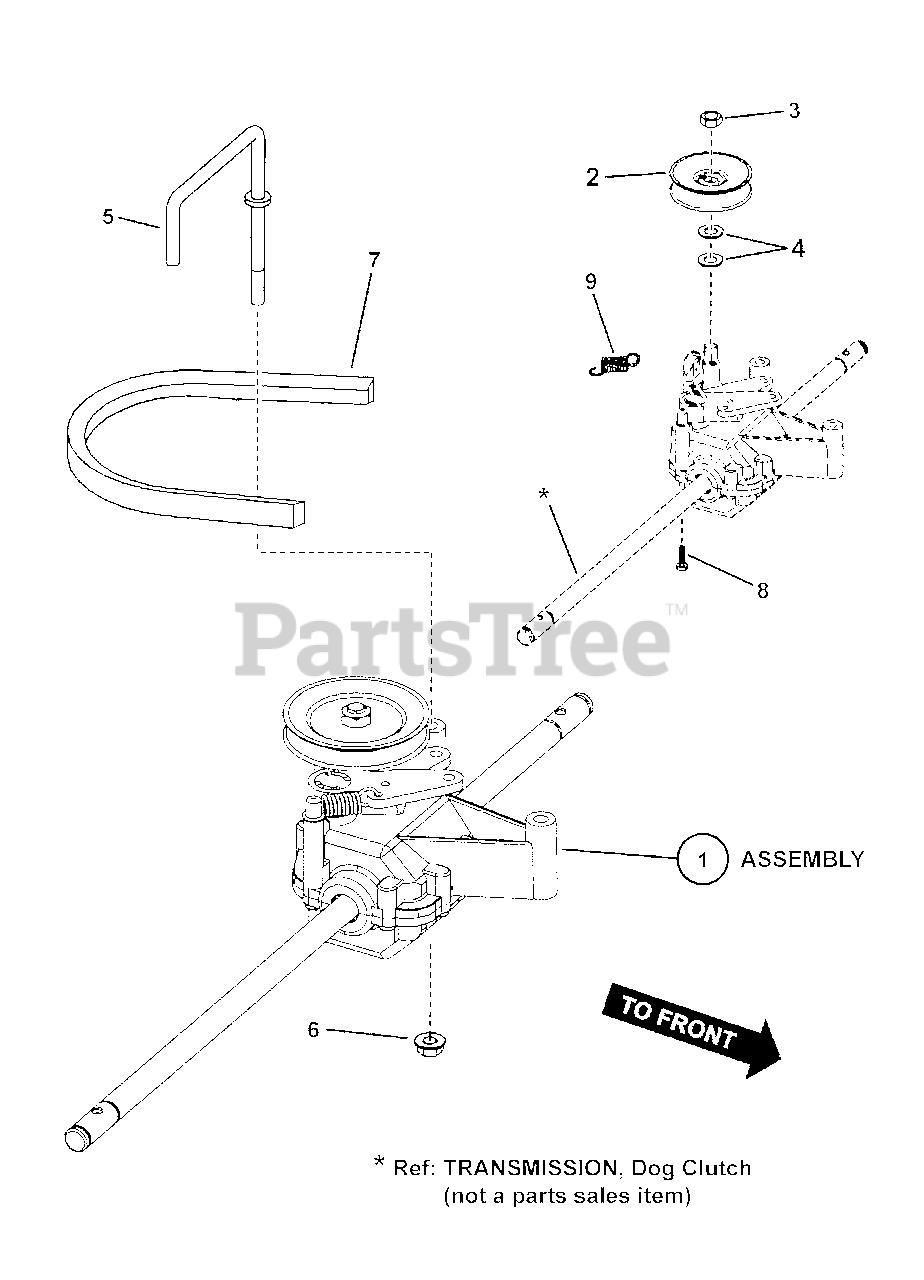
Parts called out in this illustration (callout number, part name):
1	TRANSMISSION, LC Walk, Variable Speed
2	PULLEY, Transmission
3	NUT, 3/8-16 Hex Center Lock Jam
4	WASHER, .390 I.D.
5	BELT GUIDE, Variable Speed
6	NUT, 1/4-20 Hex Top Lock Flange
7	* BELT, 3L, Traction Drive
8	SCREW, 7mm x 1 x .550 AB Point
9	SPRING, Return, Clutch
